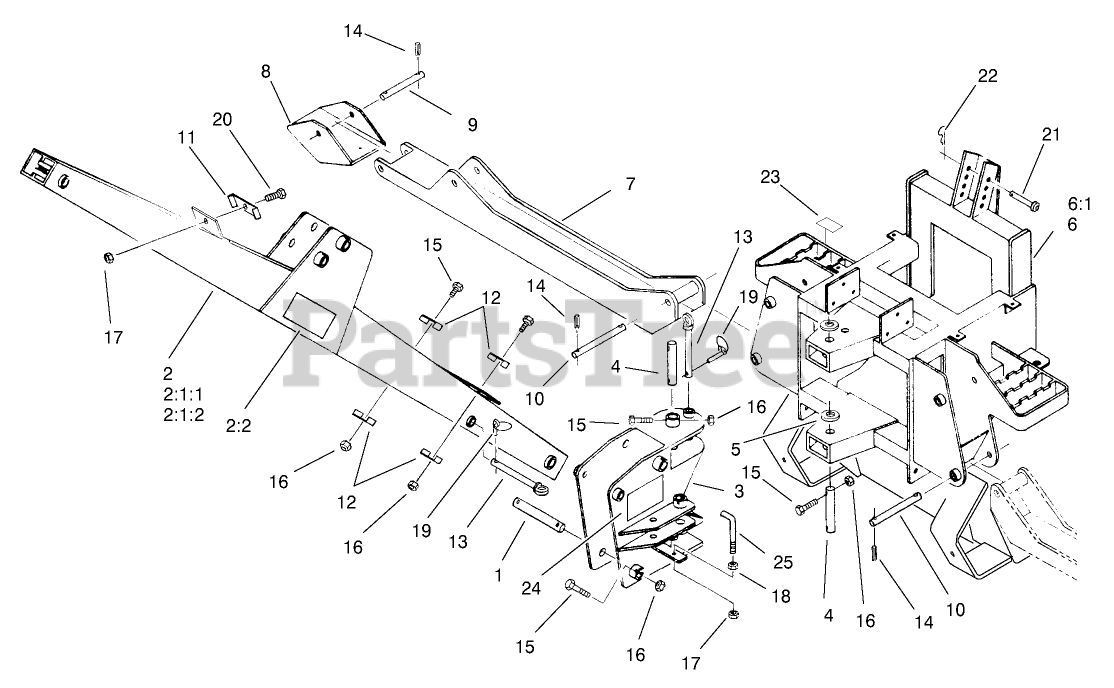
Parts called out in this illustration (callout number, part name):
1	PIN-BUCKET
2	BOOM ASM
2:2	DECAL-WARNING
3	SWIVEL ASM
4	PIN-PIVOT
5	WASHER-THRUST
6	BOX FRAME ASM
7	STABILIZER ASM
8	STABILIZER FOOT ASM
9	PIN-FOOT, STABILIZER
10	PIN-STABILIZER
11	BRACKET-HOSE
12	BRACKET-HOSE
13	LOCK PIN ASM
14	PIN-ROLL
15	SCREW-HH
16	NUT-LOCK
17	NUT-LOCK, NI
18	NUT-HEX
19	PIN-LYNCH
20	SCREW-HH
21	PIN-CLEVIS
22	PIN-HAIR
23	DECAL-WARNING
24	DECAL-PLACEMENT, PIN
25	BRACKET-HOSE
